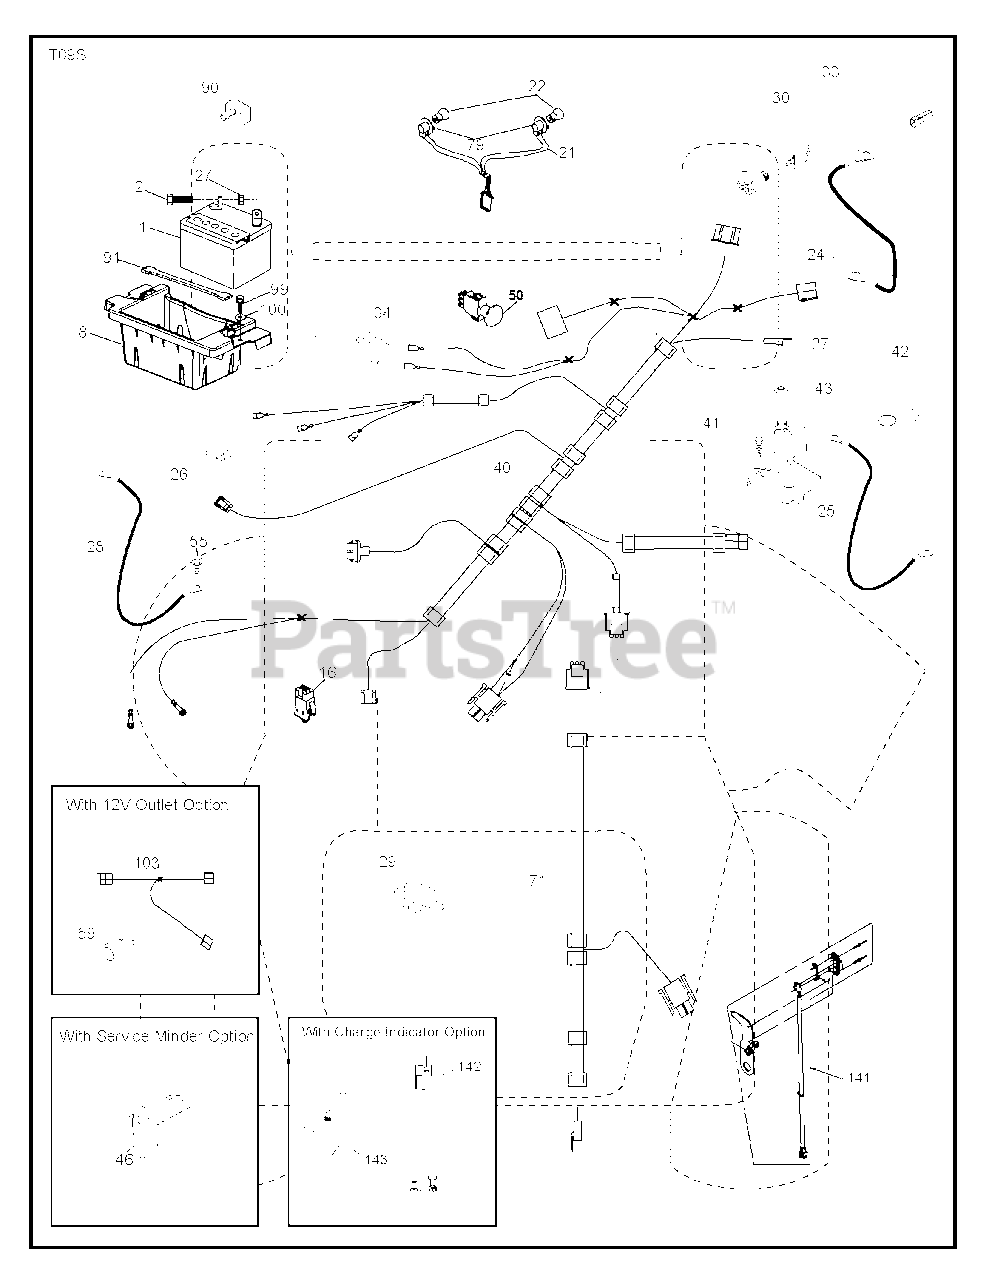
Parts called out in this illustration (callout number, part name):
1	Battery, Dry 30 Amp
2	BOLT.HEX.1/4.X.3/4.DICHROMATE
8	BOX.BATTERY.MOUNT.FRONT.LT
16	SWITCH INTERLOOK PUSH-IN
21	HARNESS ASSY LIGHT
24	CABLE.BATT.POS.WIRE.TG.DA SOL
25	CABLE.START.RED.17.5".
26	FUSE 20AMP
27	NUT
28	CABLE GROUND 6 GA 21" 90T BLK
29	SWITCH.SEAT.DELTA.OPC.
30	SWITCH.IGN.DELTA.W.LGH.ROS
33	KEY.CHAIN.BLISTER.PACK.GEN.INT
40	HARNESS.IGN.DASH.HUQ/P
41	SCREW
42	TERMINAL COVER
43	SOLENOID.W/BRASS.PLUNGER
46	RP GUAGE.SRVCMNDR.HRMTR.
50	RB PTO.SWITCH.8 TERMINAL.BLACK
55	SCREW 5/16"
71	HARNESS-CHASSIS SUB
90	COVER.TERMINAL.BATTERY
91	STRAP.BATTERY.MOUNT.FRONT(2 2)
99	SCREW HEXWSHR 1/4-20X3/4
